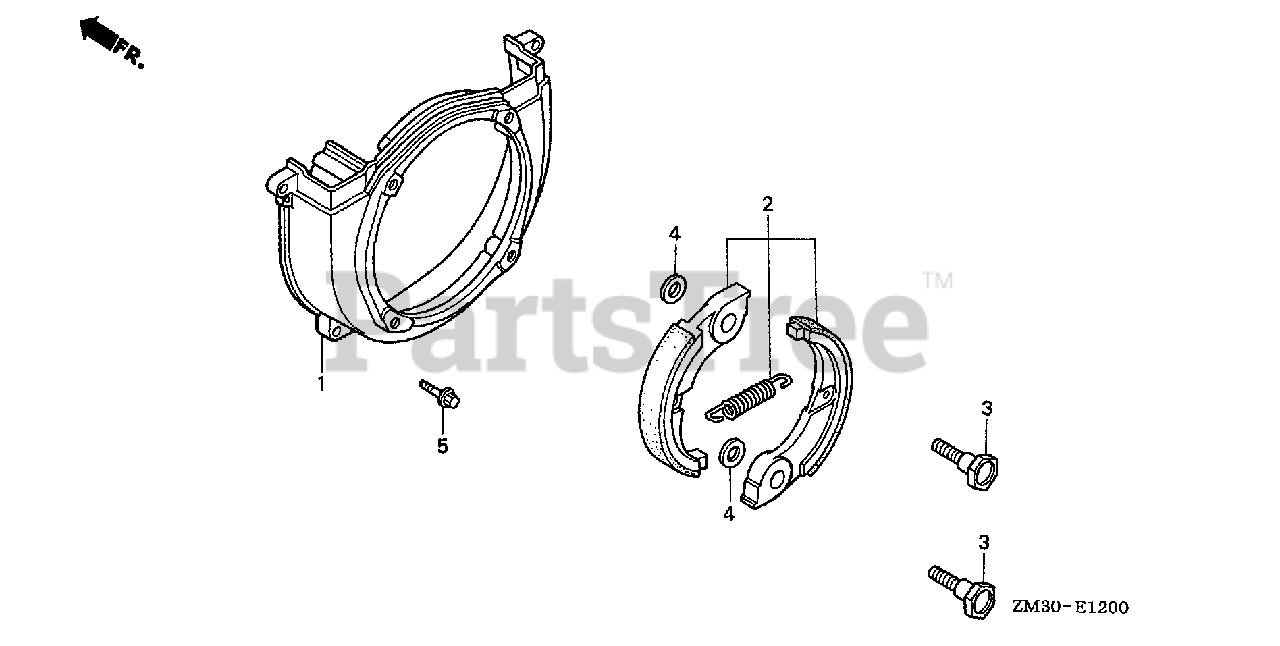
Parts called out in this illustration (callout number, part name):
1	COVER, FAN
2	CLUTCH ASSY.
3	BOLT, CLUTCH (6MM)
4	WASHER, CLUTCH (6X15)
5	BOLT, FLANGE (5X18)
